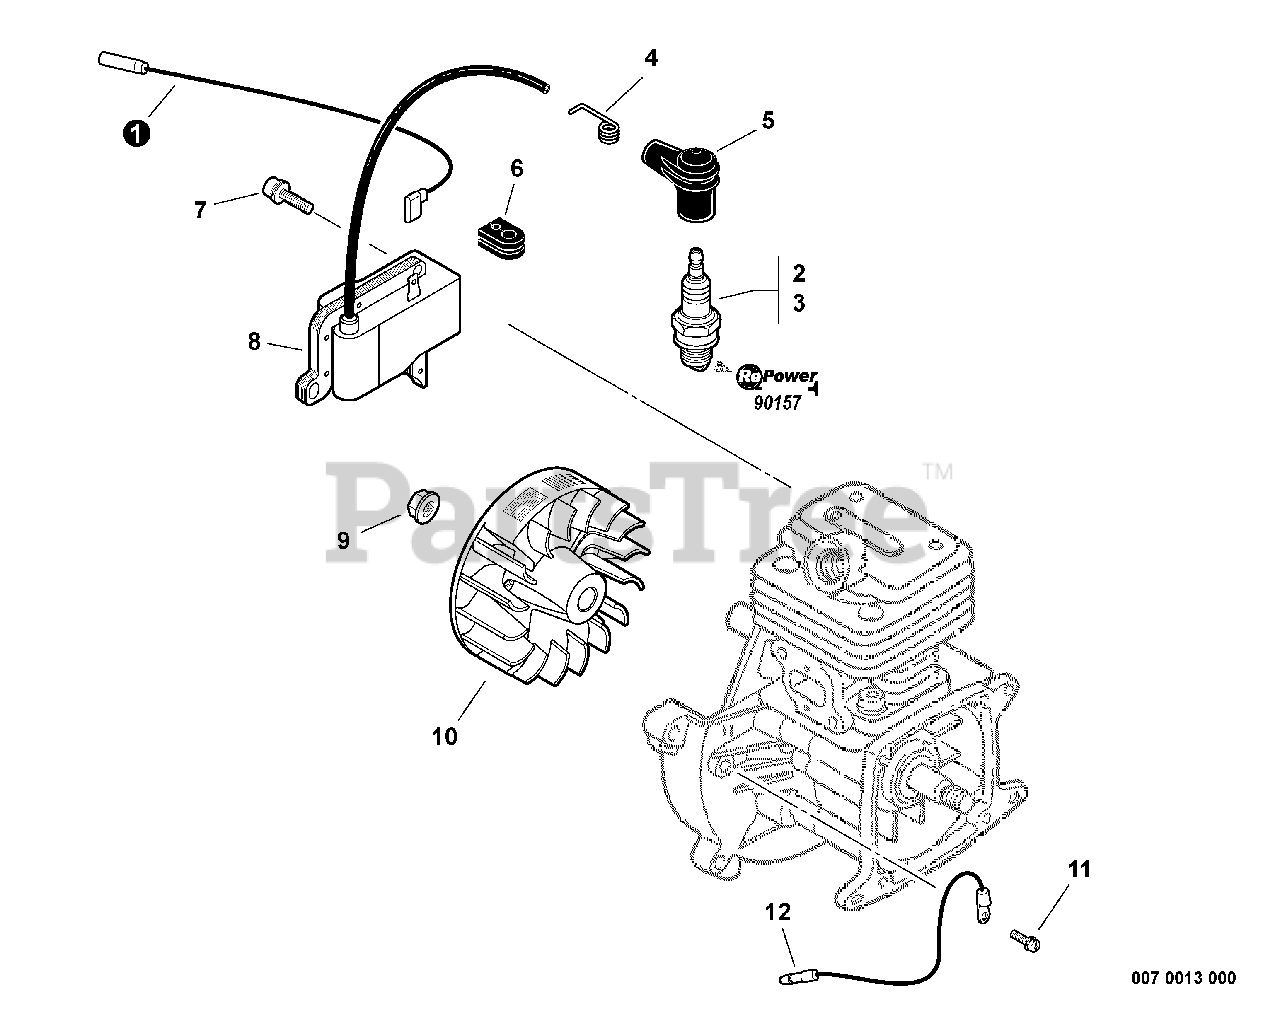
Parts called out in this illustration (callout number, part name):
1	LEAD - IGNITION
2	SPARK PLUG -- BPM-7Y
3	SPARK PLUG -- BPMR-7A
4	TERMINAL, SPARK PLUG CAP
5	CAP, SPARK PLUG
7	SCREW - 5X16
8	COIL, IGNITION
9	NUT - 8 -- FLANGE
10	FLYWHEEL
11	SCREW - 5X10
12	LEAD - GROUND
13	RePower TUNE-UP KIT
